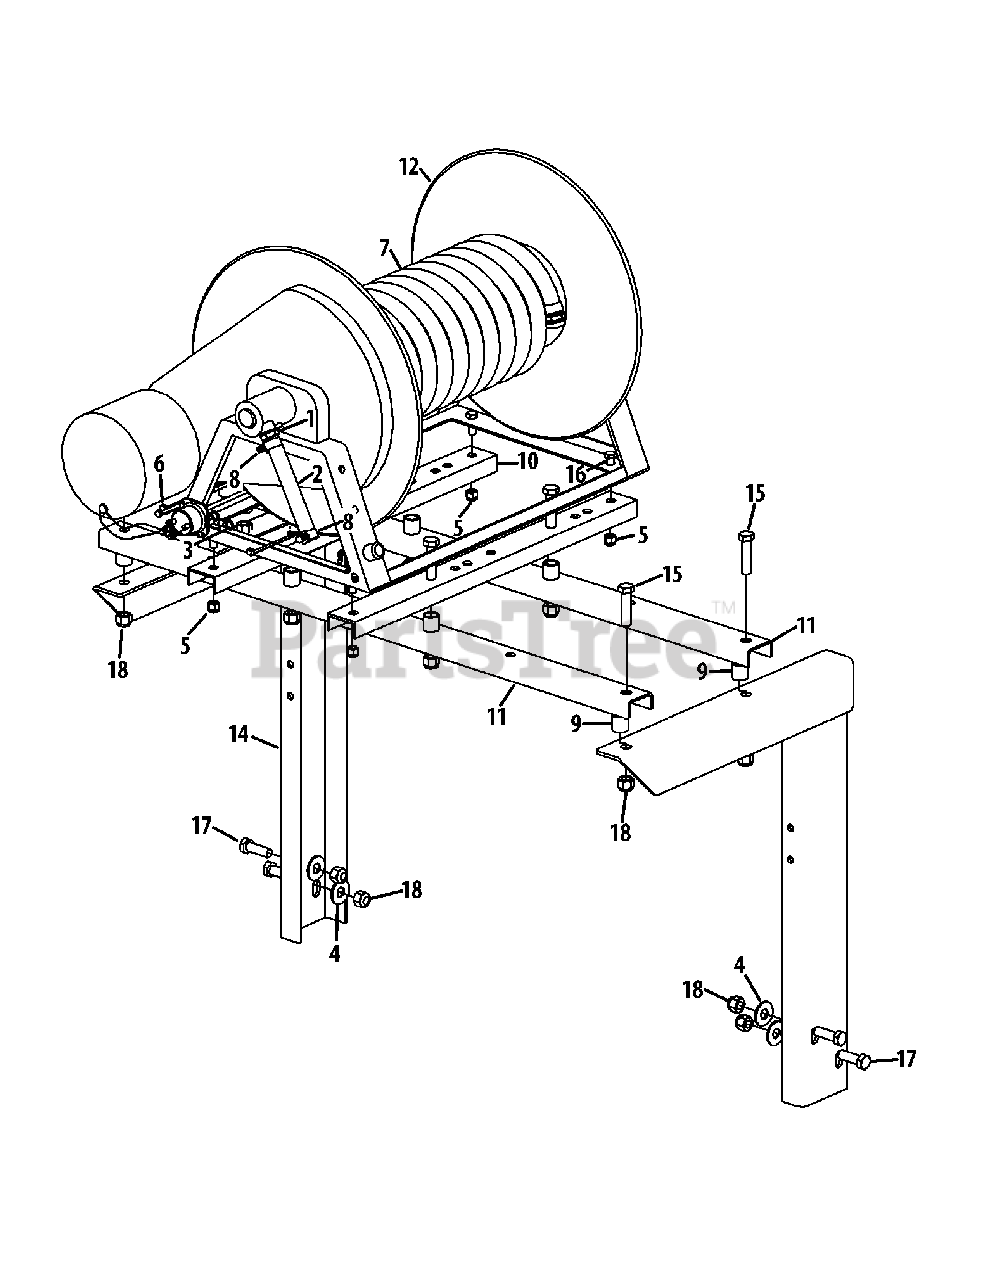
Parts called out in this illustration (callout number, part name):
1	Hose Barb, 1/2 x 1/2
2	Hose, 1/2
3	Ring Terminal, 3/8
4	Washer, .563 x 1.38 x .109
5	Lock Nut, 3/8-16
6	Cable Tie
7	Hose Assembly, 1/2 x 300
8	Hose Clamp
9	Spacer, .635 x .875 x .860
10	Reel Mounting
11	Reel Crossmember
16	Hex Screw, 3/8-16 x 1.00
17	Hex Screw, 1/2-13 x 1.50
18	Hex Lock Nut, 1/2-13
